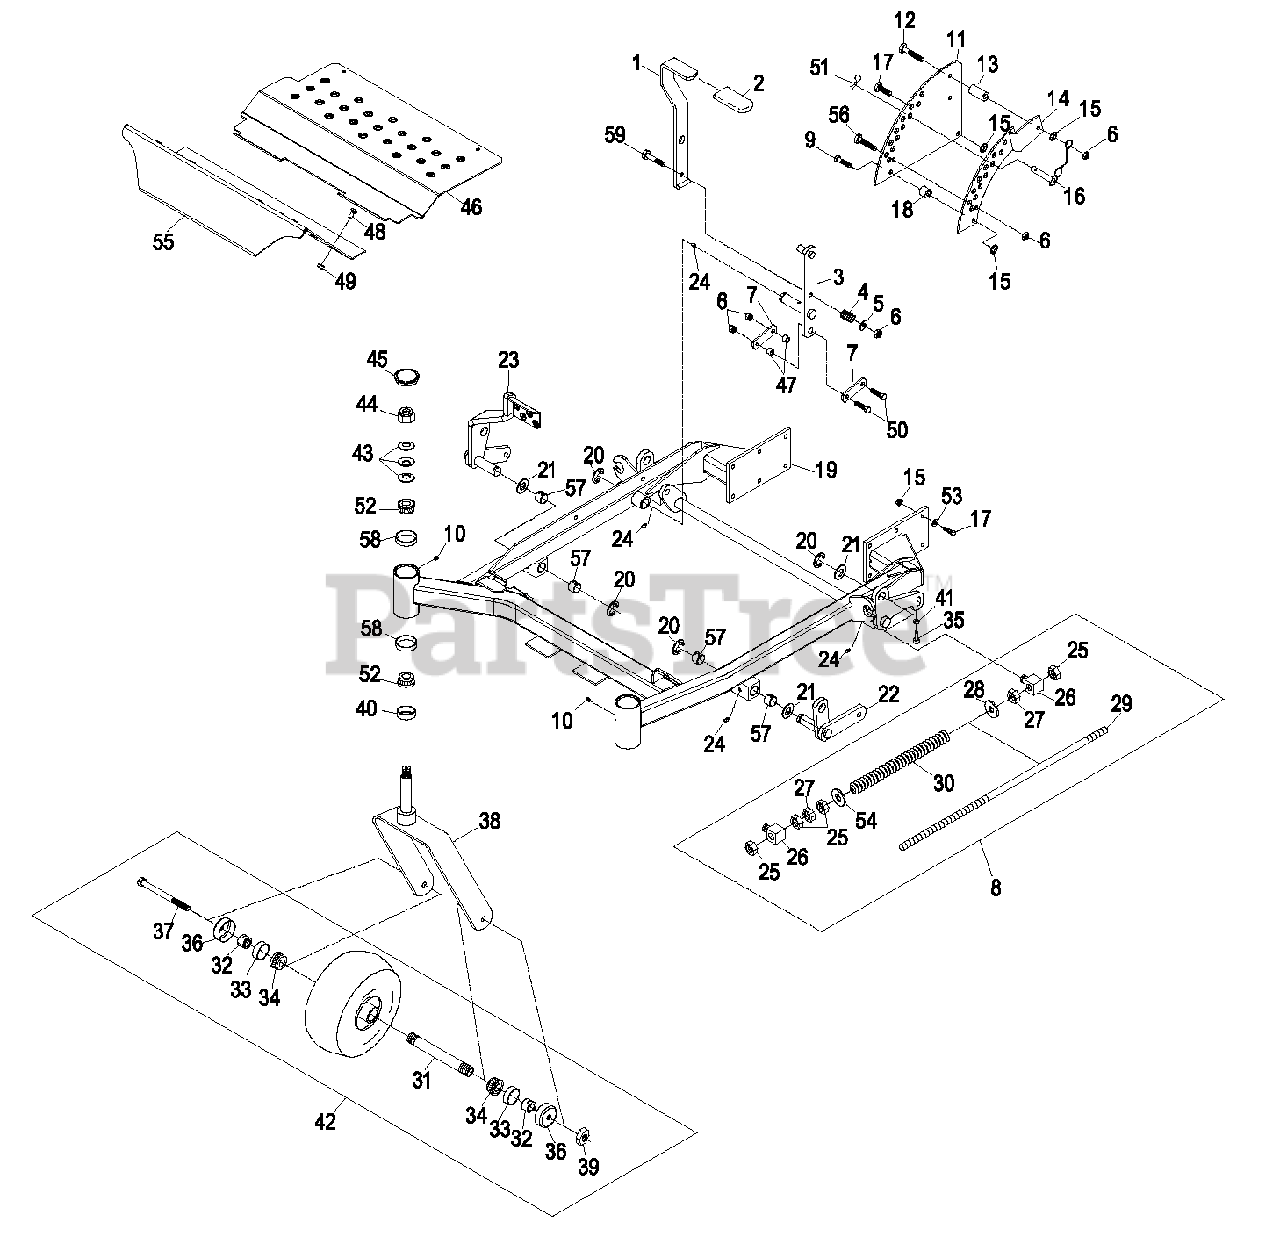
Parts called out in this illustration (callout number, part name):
1	ASM, LIFT LEVER / GRIP
2	GRIP-LEVER, LIFT
3	Arm Wldmt, Deck Lift
4	SPRING-COMPRESSION
5	WASHER-FLAT
6	NUT-LOCK, NI
7	ARM-LIFT, DECK
8	FRONT SPRING ASM
9	SCREW-HH
11	PLATE-LIFT, DECK
12	SCREW-HH
13	BUSHING-LEVER, LIFT
14	PLATE-LIFT, DECK W/DECAL
15	NUT-HHF, WHIZ
16	PIN-HITCH (W/LANYARD)
17	SCREW-HH
18	BUSHING-LEVER, LIFT
19	ASM, FRONT FRAME 50"
20	RING-RETAINING, EXT
21	WASHER-FLAT
22	WLD,SHAFT LH
24	FITTING-GREASE
25	NUT-HEX
26	SWIVEL-DECK MOUNT, REAR
27	NUT-JAM
29	ROD-LIFT, DECK
30	SPRING-COMPRESSION
32	SPACER-NUT
33	SEAL-CASTER
34	BEARING-CONE, TAPERED ROLLER
35	SCREW-HSH
36	GUARD-SEAL
37	SCREW-HH
39	NUT-HEX
40	SEAL-GREASE
41	NUT-JAM
43	WASHER-BELLVILLE
44	NUT-LOCK, NI
45	CAP-GREASE
46	ASM, FLOORPAN LIFTOUT W/D
47	BUSHING
48	BOLT-CARR
50	SCREW-HH
51	PIN-COTTER
52	Cone-Bearing Tapered Roller
53	WASHER-BELLEVILLE
54	WASHER-FLAT
55	ASM, FLOORPAN FRONT W/DEC
56	SCREW-HH
57	BUSHING,SPRING
58	CUP-BEARING
59	SCREW-HH
